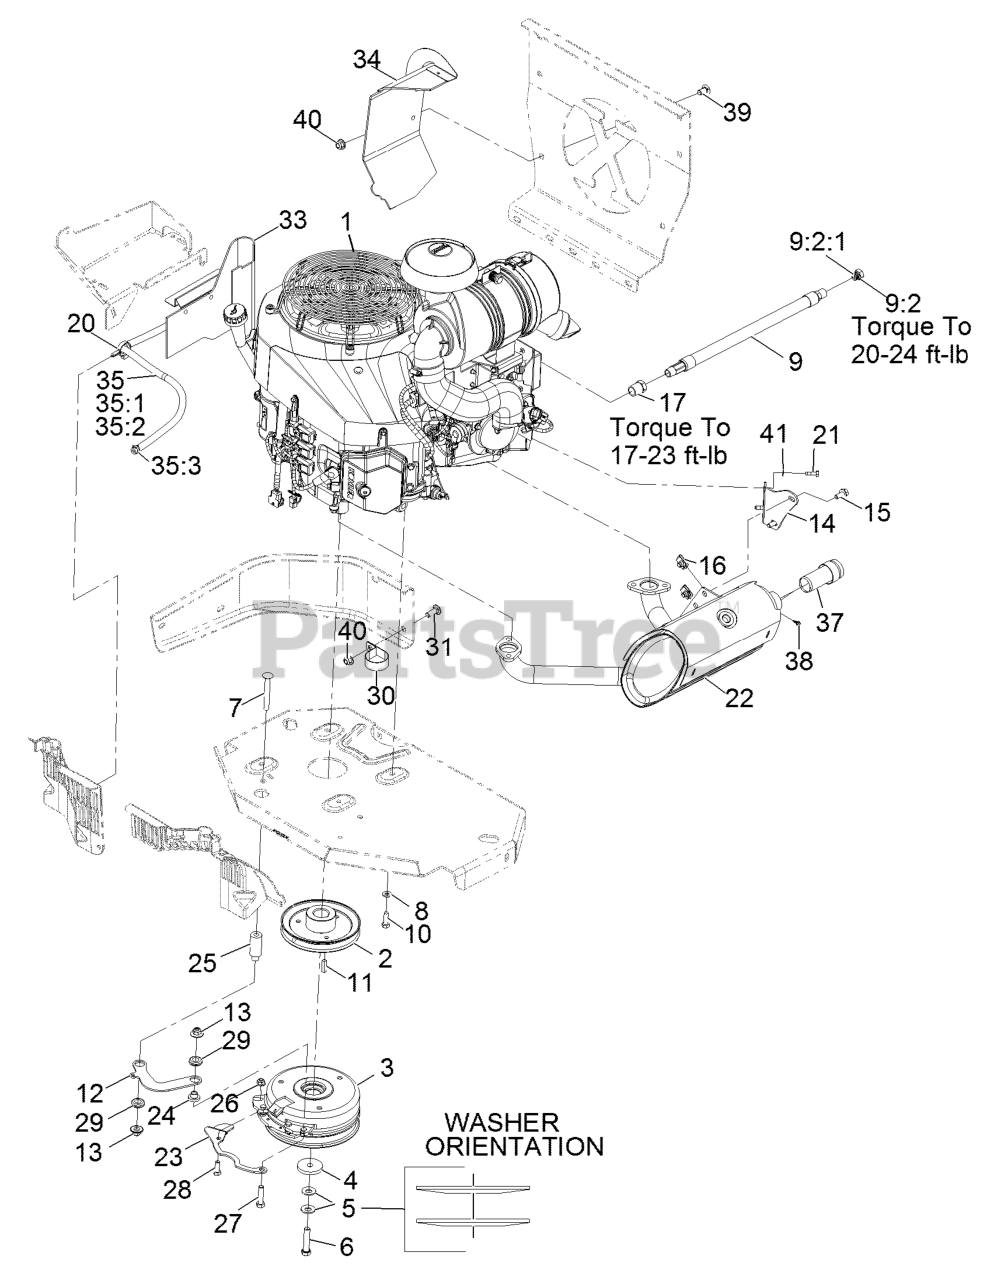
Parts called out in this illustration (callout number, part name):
1	Engine-Kohler, Ecv940 Efi-Egov
2	SHEAVE
4	WASHER-CLUTCH
5	WASHER-SPRING
6	SCREW-HH 7/16-20 X 1 1/2 W/LOCTITE
7	SCREW-CARR
8	WASHER-SPRING
9	OIL DRAIN HOSE ASM
9:2	PLUG-HH
9:2:1	O-RING
10	SCREW-HH
12	LINK-ANCHOR, CLUTCH
13	Nut-Nyloc 3/8-16 Flg
14	BRACKET-MUFFLER
15	SCREW-HHF
17	BUSHING
20	CLAMP-HOSE
21	SCREW-HH M6-1 X 20Mm W/Patch
23	BELT-GUIDE
26	NUT-HF, NI
27	SCREW-HH
28	SCREW-HH
29	GROMMET-RUBBER
30	CLAMP-R
31	SCREW-CARR
33	BAFFLE-RH
35	FUEL LINE ASM
35:1	HOSE-FUEL
35:2	SLEEVE-THERMAL
35:3	CLAMP-HOSE
37	ARRESTOR-SPARK
38	SCREW-HWH
39	SCREW-CARR
40	NUT-HF, NI
41	WASHER-SPRING
